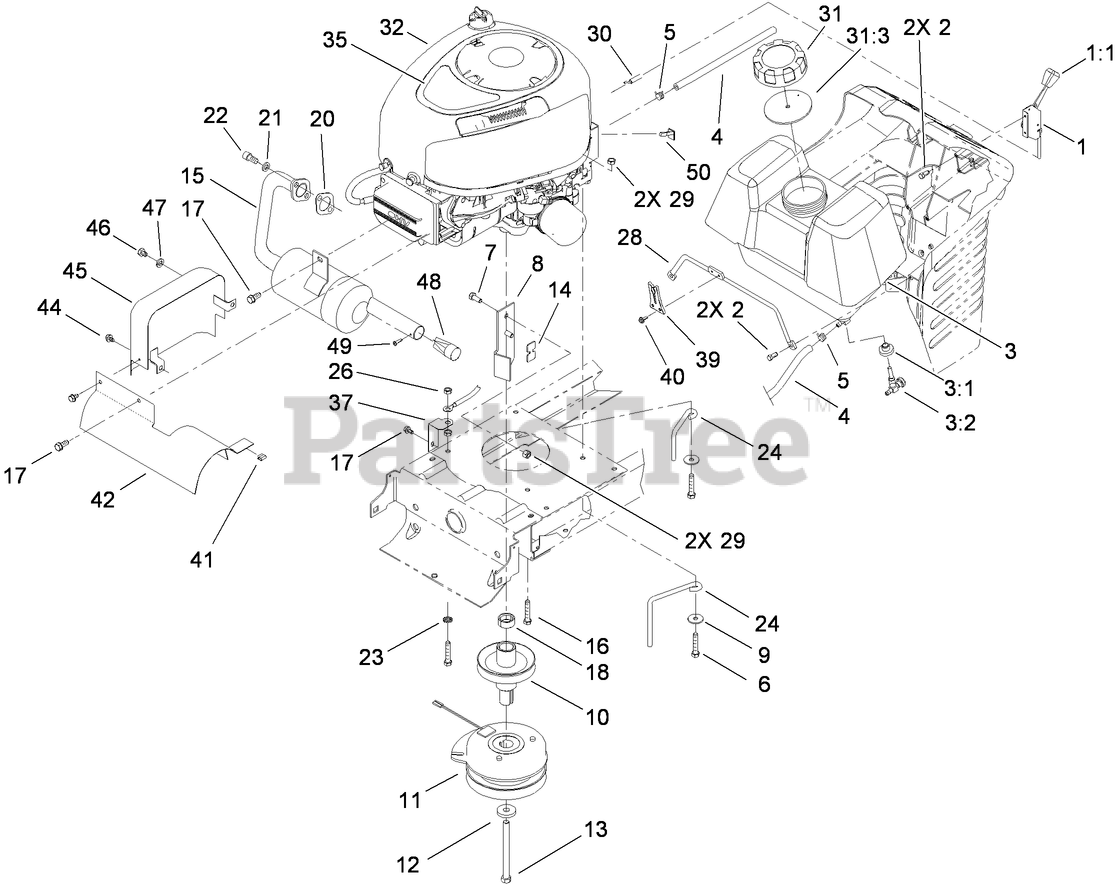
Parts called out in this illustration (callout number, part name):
1	THROTTLE CONTROL ASM
2	SCREW-SPECIAL
3	GAS TANK ASM
3:1	BUSHING
3:2	VALVE-FUEL
4	HOSE-FUEL
5	CLAMP-HOSE
6	SCREW-HH
7	SCREW-HH
8	STOP-CLUTCH
9	WASHER-PIVOT
10	PULLEY-ENGINE
11	CLUTCH-PTO, ELECTRIC
12	WASHER
13	SCREW-HH
14	BUMPER
15	MUFFLER-EXHAUST
16	SCREW-HWH, TAPTITE
17	SCREW-HWH
18	Spacer
20	GASKET-EXHAUST
21	WASHER-LOCK
22	SCREW-HSH
23	WASHER-LOCK
24	GUIDE-BELT, RH
26	NUT-KEPS
28	ROD-TANK, GAS
29	NUT-LOCK, NI
30	THROTTLE CABLE ASM
31	GAS CAP ASM
31:3	GASKET-CAP, GAS
32	Loose Parts Package
35	DECAL-ENGINE
37	BRACKET-GROUND
39	LATCH-HOOD
40	SCREW-HWH
41	CLIP-TINNERMAN
42	EXHAUST SHIELD ASM
44	SCREW-HWHTF
45	HEAT SHIELD ASM
46	SCREW-HH
47	WASHER-LOCK
48	SCREEN-SILENCER, EXHAUST
49	SCREW-THD FORM, HWH
50	REDUCER-THROTTLE, RPM
